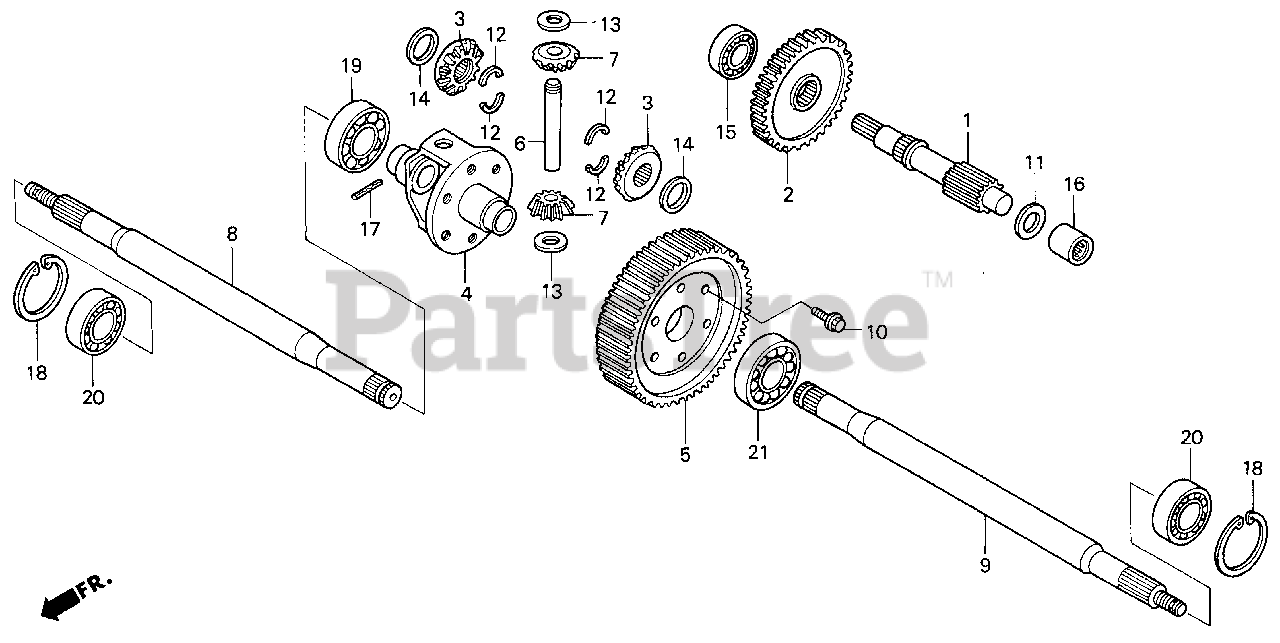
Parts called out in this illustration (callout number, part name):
1	COUNTERSHAFT
2	GEAR, COUNTERSHAFT DRIVEN (52T)
3	GEAR, DIFFERENTIAL
4	CASE, DIFFERENTIAL GEAR
5	GEAR, FINAL DRIVEN (59T)
6	SHAFT, DIFFERENTIAL
7	PINION, DIFFERENTIAL
8	SHAFT, R. AXLE
9	SHAFT, L. AXLE
10	BOLT, SPECIAL (10X20)
11	WASHER, THRUST (18MM)
12	COTTER (15MM)
13	WASHER A, DIFFERENTIAL PINION (14.2X26X0.7)
13	WASHER B, DIFFERENTIAL PINION (14.2X26X0.8)
13	WASHER C, DIFFERENTIAL PINION (14.2X26X0.9)
13	WASHER D, DIFFERENTIAL PINION (14.2X26X1.0)
14	WASHER, DIFFERENTIAL GEAR
15	BEARING, RADIAL BALL (60/22)
15	BEARING, RADIAL BALL (60/22) (TMB)
16	BEARING, NEEDLE (18X25X17)
17	PIN, SPRING (4X32)
18	CIRCLIP (INNER) (52MM)
19	BEARING, RADIAL BALL (6006)
20	BEARING, RADIAL BALL (6205)
21	BEARING, RADIAL BALL (6206)
